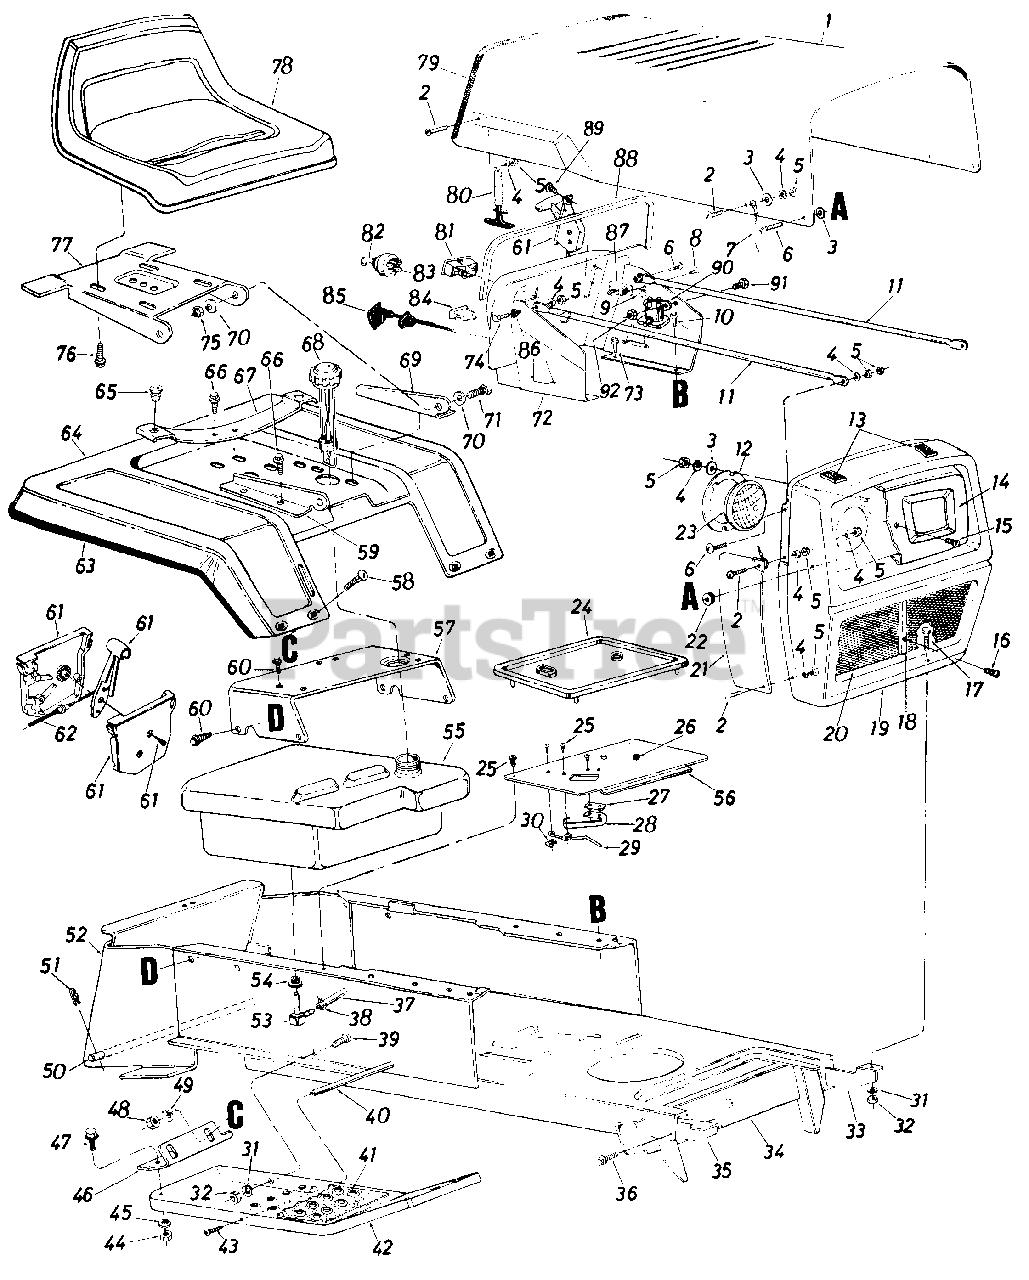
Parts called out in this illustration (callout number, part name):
3	Fl-Wash. 1/4" I.D.
4	L-Wash. 1/4" I.D.
5	Hex Nut 1/4-20 Thd.
6	Truss Mach. Scr. 1/4-20 x .75" Lg.
7	Hood Stop
8	Hex Tap Scr. #10 x .50" Lg.
9	Speed Nut #10Z
10	Hex Thd. Rolling Scr. 1/4" x .50" Lg.
11	Grille Positioning Rod
12	Head Lamp Retainer
13	PVC Foam Strip 1/2" x 1.00" x 2.00" Lg.
14	Head Lamp Bezel
15	Truss Mach. Scr. #10-24 x .38" Lg.
16	Truss Mach. Scr. #10-24 x .62" Lg.
17	Hex Bolt 5/16-18 x .75" Lg.
18	Center Moulding
19	Grille-Chrome
20	Grille Insert-Screen
21	Grille Side Panel-R.H.
22	Rubber Wash. .50" I.D. x 1.0" O.D. .25 Thk.
23	Head Lamp
24	Trans. Cover-Bezel
25	Hex AB-Tap Scr. #8 x .50" Lg.
26	Snap Bushing
27	Insulator Nut Plate
28	Switch Spring
29	Shift Lever Spring
30	Speed Nut #10-24 U-Type
31	L-Wash. 5/16" I.D.*
32	Hex Nut 5/16-18 Thd.
33	Grille Mount Brkt.-L.H.
34	Lower Frame Ass'y.
35	Grille Mount Brkt.-R.H.
36	Hex Thd. Rolling Scr. 5/16" x.75" Lg.
37	Gas Line 46" Lg.
38	Hose Clamp 3/8"
39	Hex Bolt 5/16-18 x .75" Lg.
40	Running Board Rod
41	Foot Pad
42	Running Board-R.H.
43	Truss Mach. Scr. 5/16-18 x .75" Lg.
44	Hex Nut 5/16-18 Thd.
45	Bell-Wash. .34" I.D. x .87 O.D.
48	Hex Nut 1/4-20 Thd.
49	L-Wash. 1/4" I.D.
50	Hitch Rod
51	Internal Cotter Pin
52	Hitch Plate
53	90ø Nipple
54	Bushing
55	Fuel Tank
56	Trans.-Cover
57	Seat Mounting Channel
58	Carriage Bolt 1/4-20 x .50" Lg.*
59	Seat Bracket-R.H.
60	Hex Thd. Rolling Scr. 5/16-24 x .75" Lg.
61	Throttle Control Box Ass'y.
62	Throttle Control Wire
63	Trim Strip-81"
66	Hex Wash. Hd. Self-Tap Scr. 5/16-18 x .50" Lg.
67	Seat Spring
68	Gas Cap w/Gauge
69	Seat Bracket-L.H.
70	Bell-Wash. .34" I.D. x .88" O.D.
71	Hex Bolt 5/16-18 x .75" Lg.*
72	Dash Panel Ass'y.
73	Hex Thd. Rolling Scr. 5/16-24 x .75" Lg.
74	Truss Mach. Scr. 1/4-20 x 1.0" Lg.
75	Hex Cent. L-Nut 5/16-18 Thd.
76	Hex Wash. Hd. AB-Tap Scr. 3/8 x .75" Lg.
77	Seat Pivot Bracket
78	Seat Ass'y.
79	Vinyl Moulding Strip-30"
80	Hood Latch Ass'y.
81	Ammeter
82	Ignition Key
83	Ignition Switch
84	Light Switch
85	Choke Control Comp.
86	External Wash. 1/4" I.D.
87	Circuit Breaker 8 Amp.
88	Vinyl Moulding Strip-29"
89	Truss Mach. AB-Tap Scr. #10 x .50" Lg.
90	Solenoid
91	Hex Bolt 1/4-20 x .50" Lg.
92	Hex Sems Nut 1/4-20 Thd.
